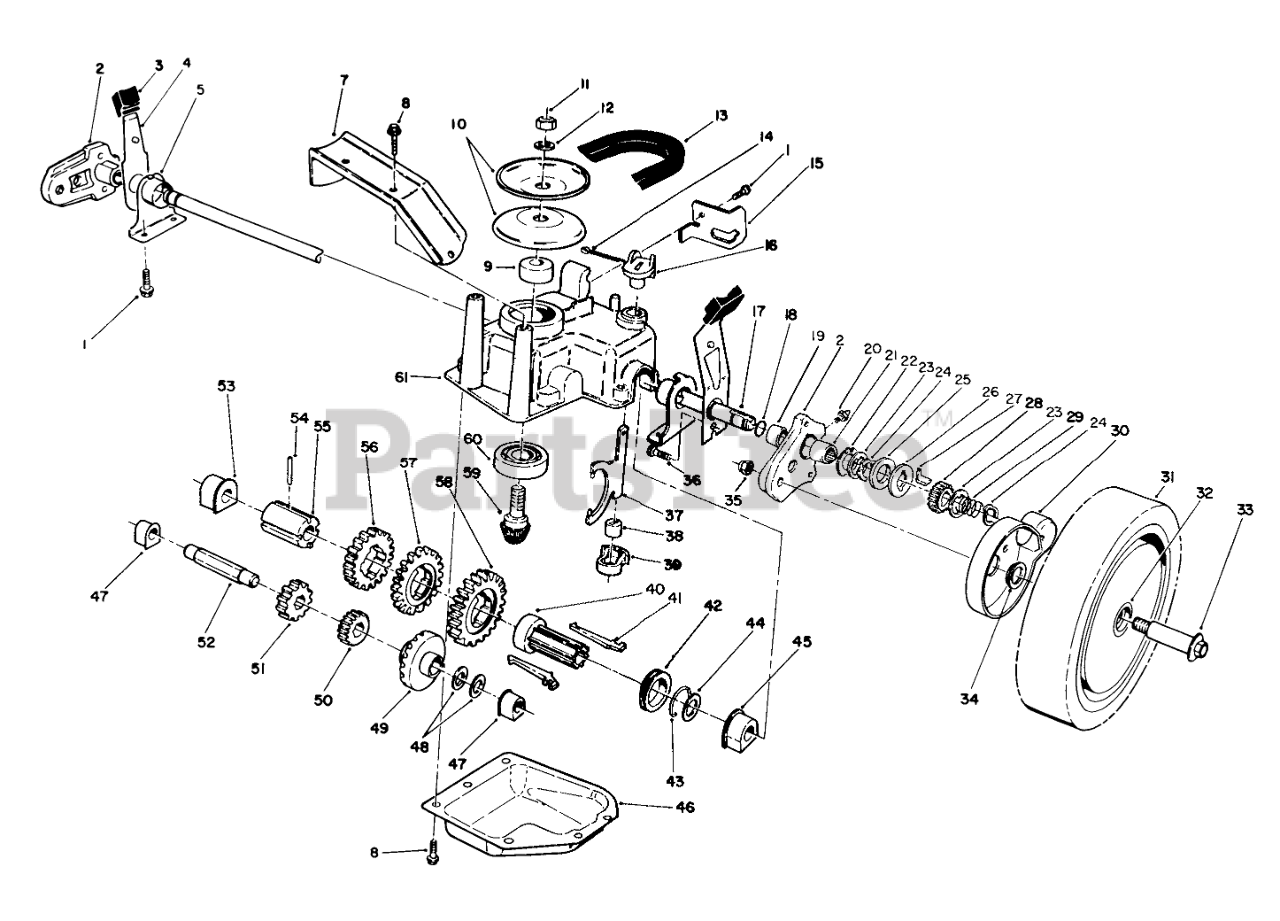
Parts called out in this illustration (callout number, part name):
1	SCREW-HWHTF
2	Pivot Arm Assembly (Incl. Ref. #19-21)
3	KNOB-ARM
4	SPRING ARM ASM
5	CAP-END
7	Bracket-BeltGuide
8	SCREW-HWHTF
9	SPACER
10	Pulley Half
11	NUT-HEX
12	WASHER-FLAT
13	V-BELT
14	PIN-COTTER
15	RETAINER-CABLE
16	LEVER-SHIFT
17	SHAFT-OUTPUT
18	O-RING
19	BUSHING
20	FITTING-GREASE
21	BEARING-ROLLER
22	WASHER-ARM, PIVOT
23	WASHER-THRUST, KEYED
24	RING-CLIP, LOCKING
25	RING-FRICTION
26	WASHER-CLUTCH
27	KEY-ROCKING, LH
28	GEAR-PINION
29	SPRING-COMPRESSION
30	COVER-WHEEL
31	Wheel Tire & Gear Assy. (Incl. Ref. #32)
32	BUSHING
33	WHEEL BOLT
34	SPACER-COVER, WHEEL
35	NUT-LOCK
36	SCREW-HSH, THREAD FORMING
37	YOKE-SHIFT
38	BUSHING-YOKE
39	RETAINER-FORK, SHIFT
40	SLEEVE-KEY, SHIFT
41	KEY-SHIFT
42	COLLAR-SHIFT
43	CLIP-SPRING
44	WASHER-PLAIN
45	BUSHING-OUTPUT
46	Cover-Gearcase
47	BUSHING
48	WASHER-THRUST
49	Gear-Bevel
50	PINION-20T
51	PINION-25T
52	SHAFT-INTERMEDIATE
53	BUSHING
54	PIN-SPRING
55	SLEEVE-GEAR
56	GEAR-39T
57	GEAR-44T
58	GEAR-49T
59	Gear-Pinion
60	BEARING-BALL
61	CASE-GEAR, UPPER
